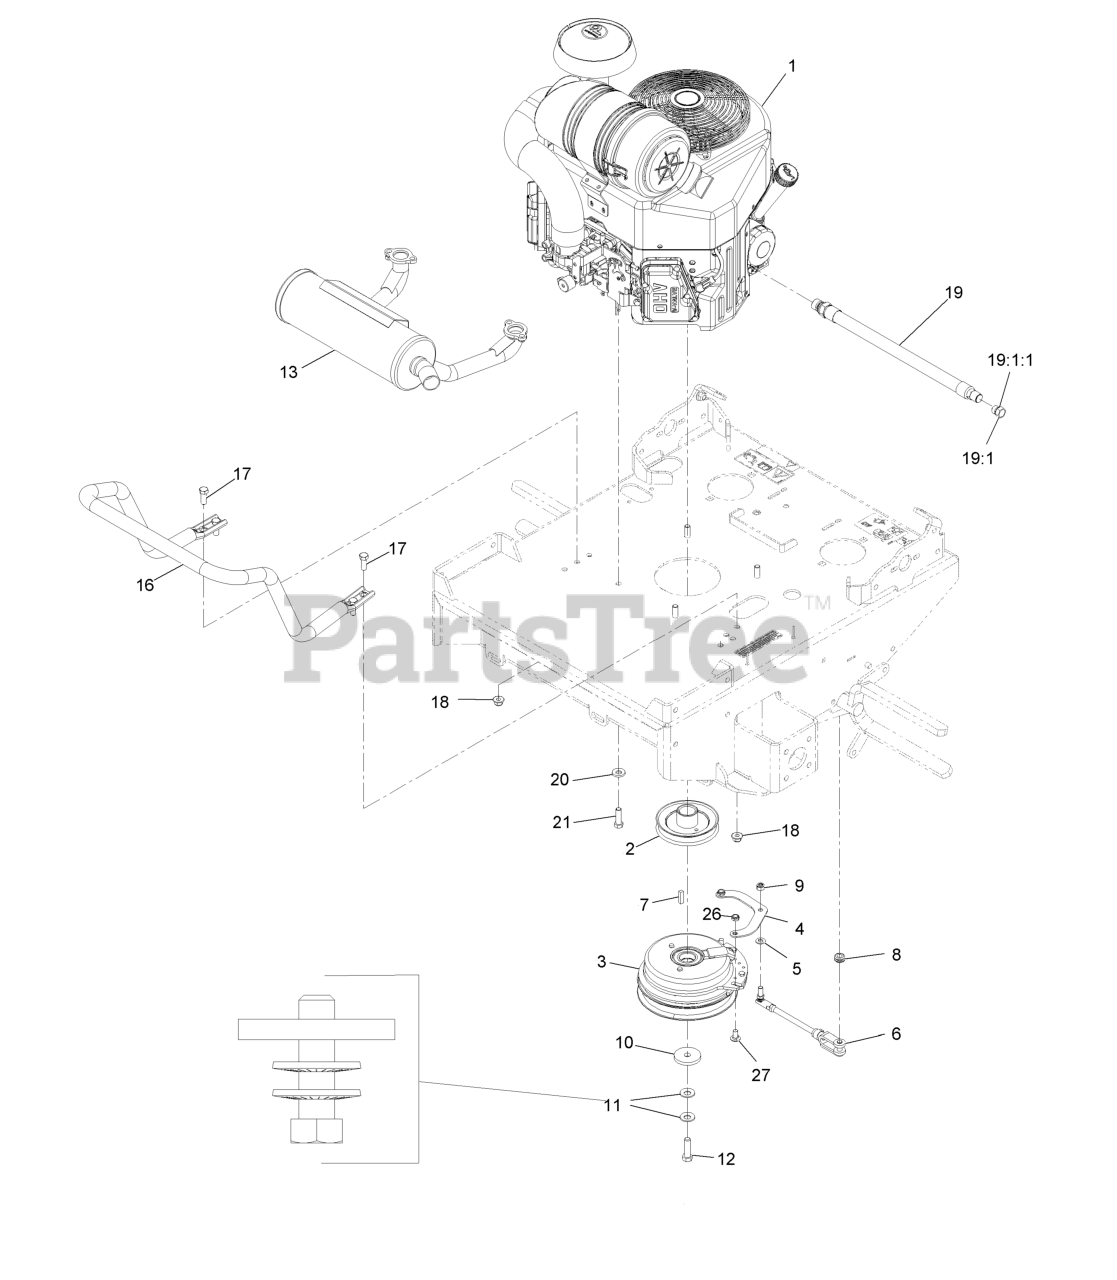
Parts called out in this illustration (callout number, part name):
2	Sheave W/ Hub
3	Clutch, 200 Ft/Lbs, 1.13
4	Strap, Clutch
5	Washer-5/16 SAE
6	ASM, Clutch Anchor
7	Key-Machine 1/4 X 1/4 X 1
8	Grommet
9	Nut-Lock 5/16-24
10	Washer-Clutch
11	Washer-Spring Disc 7/16
12	Bolt-Hex, TAP
13	Muffler,Horizontal
16	Guard-Muffler
17	Screw-HH 3/8-16 X 1
18	Nut-Nyloc 3/8-16 Flg
19	Asm-Oil Drain Hose W/Plug
19:1	Plug-W/O-Ring
19:1:1	O-Ring
20	Washer-Spring Disc 3/8
21	Screw-HH 3/8-16 X 1 1/4
26	Nut-Nyloc 5/16-18 Thin
27	Bolt-Carriage 5/16-18 X 5/8
